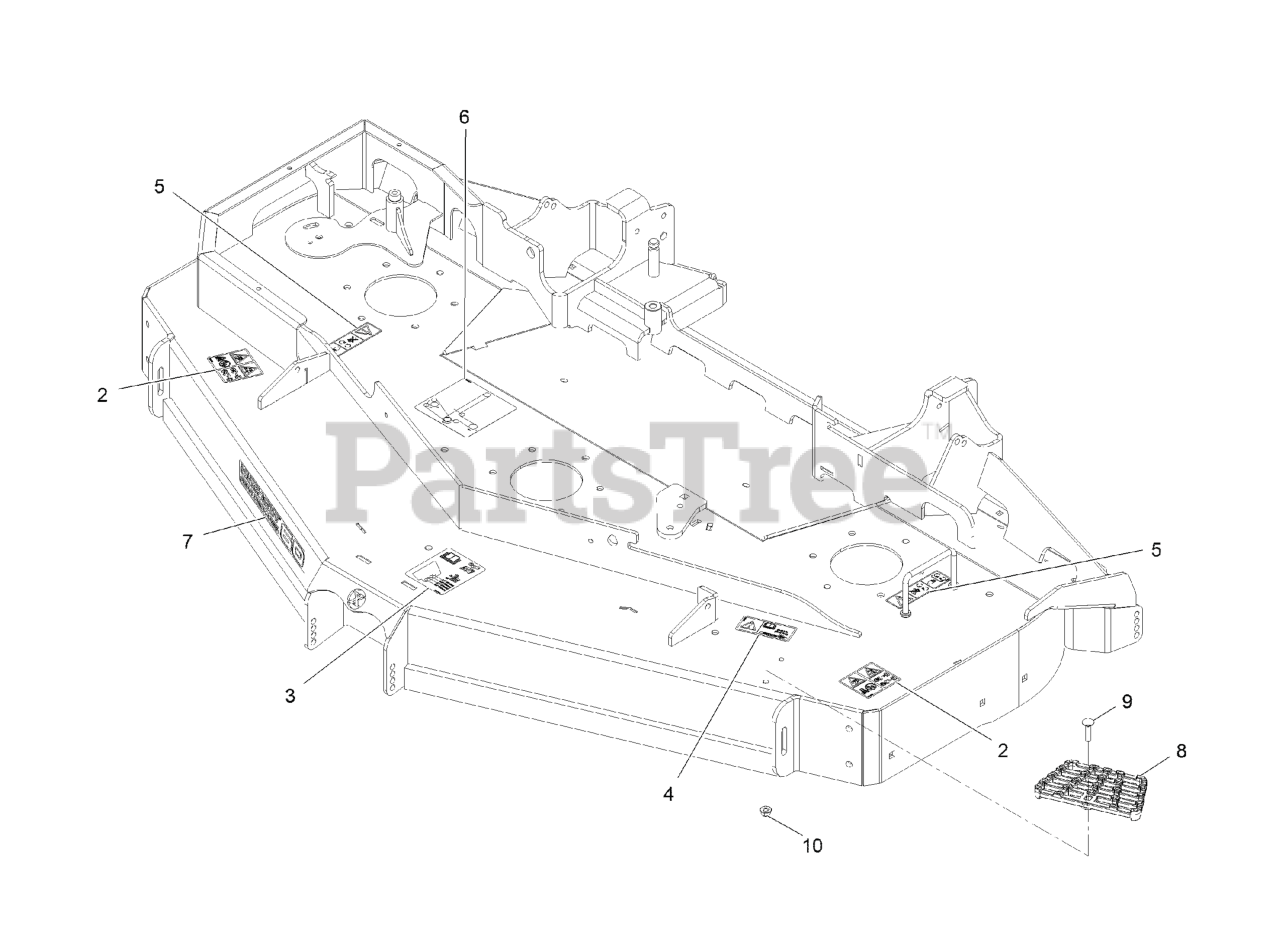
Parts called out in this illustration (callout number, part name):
2	DECAL-DANGER, THROWN OBJECT
3	DECAL-ROLLER, ANTI-SCALP
4	DECAL-TORQUE, BOLT
5	DECAL-COVER, MISSING
6	DECAL-ROUTING, BELT
7	DECAL, 60RD
8	STEP-DECK
9	Bolt-Carriage 5/16-18 X 1 1/4
10	NUT-HF, NI
